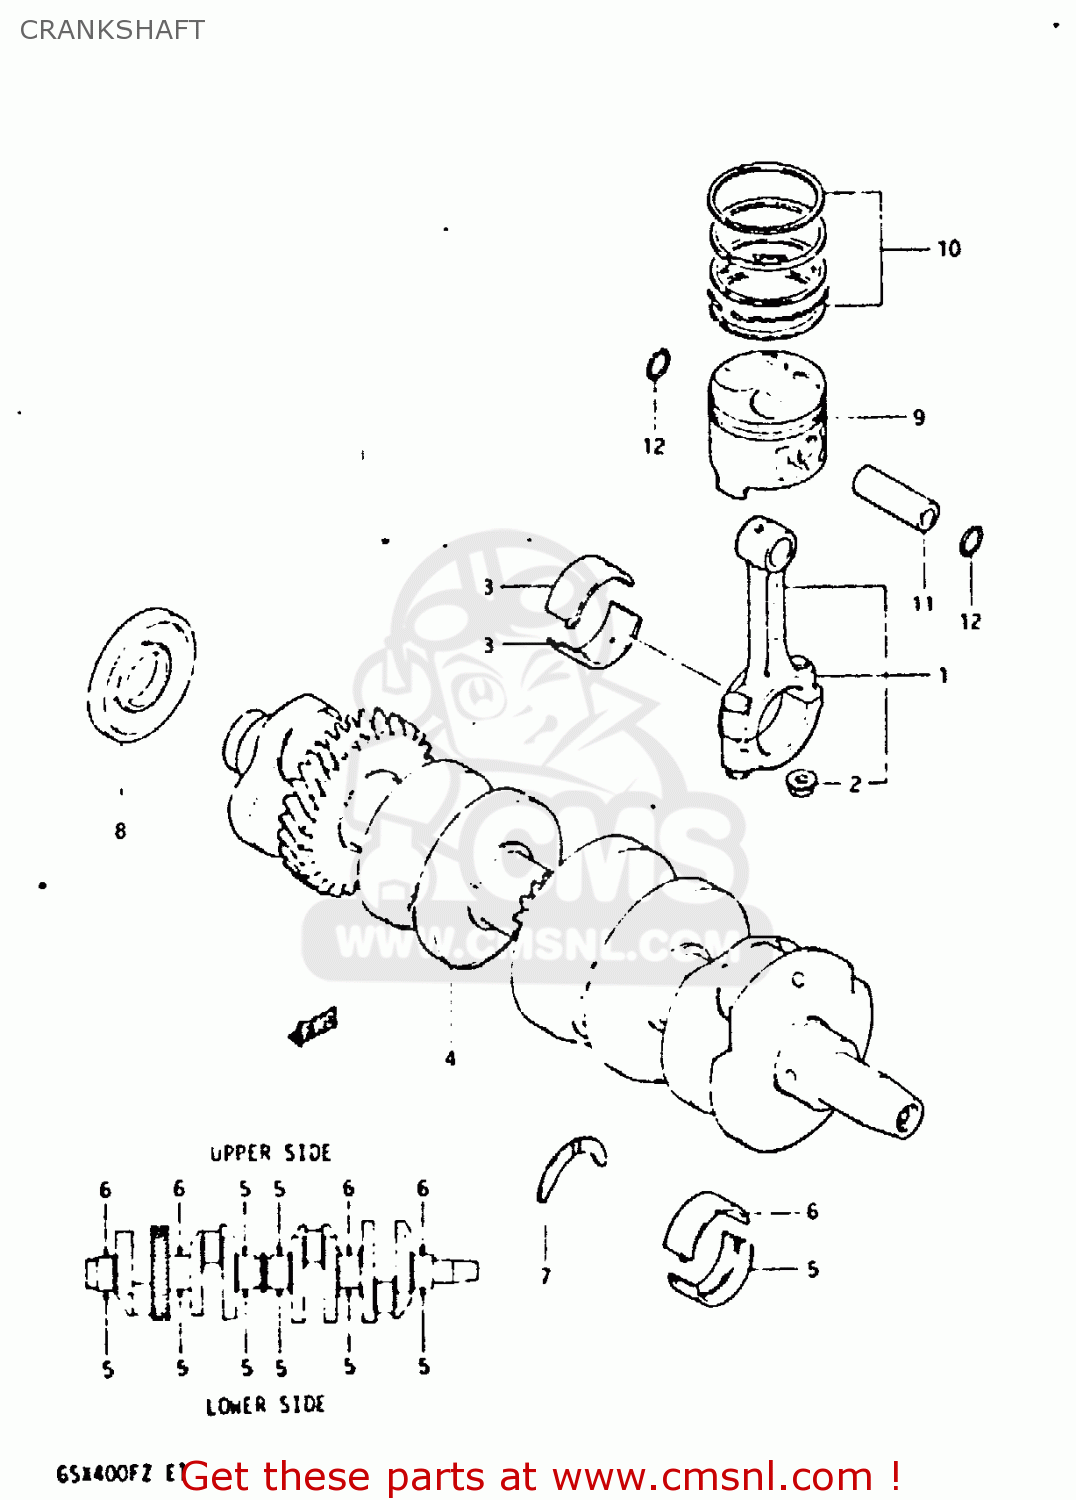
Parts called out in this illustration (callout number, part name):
1	ROD ASSY, CONNECTING
2	NUT
3	BEARING,CRANK PIN
4	CRANKSHAFT
5	METAL CRANKSHAFT
6	METAL CRANKSHAFT
7	PLATE,CRANK THRUST
8	OIL SEAL 30X56
9	PISTON 1.00
10	RING SET
11	PIN,PISTON
12	RING,SNAP 14MM
